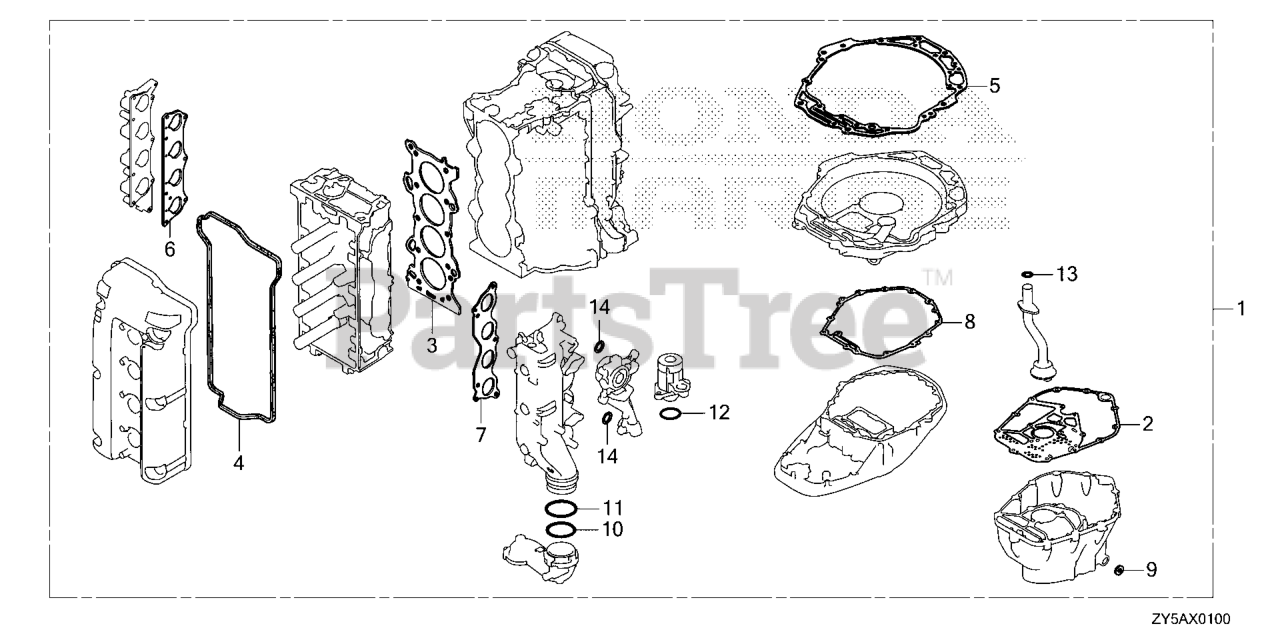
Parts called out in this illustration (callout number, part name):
1	GASKET KIT
1	GASKET KIT (BF135
2	GASKET, OIL PAN
3	GASKET, CYLINDER HEAD
4	GASKET, CYLINDER HEAD COVER
5	GASKET, OIL PUMP BODY
6	GASKET A, INJECTOR BASE
7	GASKET, EX. MANIFOLD
8	GASKET, MOUNT CASE
9	WASHER, DRAIN PLUG (12MM)
10	O-RING (76.4X3.1)
11	O-RING (79.8X3.1)
12	O-RING (59.4X3.1)
13	O-RING (20.6X2.6)
14	O-RING (22.5X2.4)
